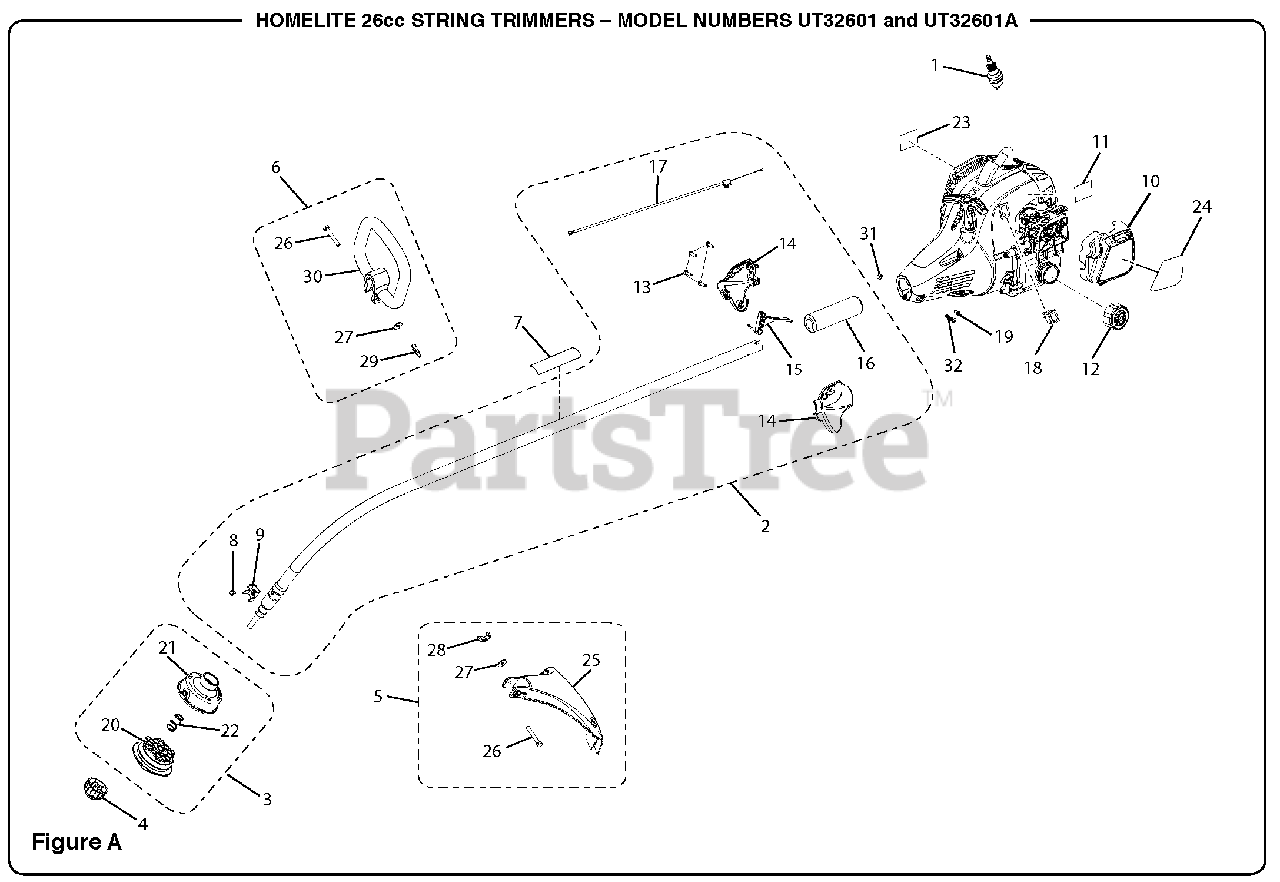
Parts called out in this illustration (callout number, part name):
1	Spark Plug (Champion RCJ6Y)
2	Boom Assembly
3	String Head Assembly
4	Spool Retainer
5	Grass Deflector Assembly
6	Front Handle Assembly
7	Icon Warning Label
8	Screw (10-32 x 3/8 in.)
10	Air Box Cover
11	Model Label (26CS)
13	Screw (M4 x 20 mm)
14	Handle Assembly
15	Throttle Trigger
16	Foam Grip
17	Throttle Cable
18	Momentary Stop Switch
19	Screw (8-16 x 5/16 in.)
20	Spool
21	String Head Housing
22	Spring
23	Combustion Warning Label
24	Starting Label
25	Grass Deflector
26	Bolt (1/4-20 x 2 in.)
28	Wing Nut (1/4-20)
29	Wing Nut (1/4-20)
30	Front Handle
31	Hex Nut (M6)
32	Screw (M6 x 20 mm)
